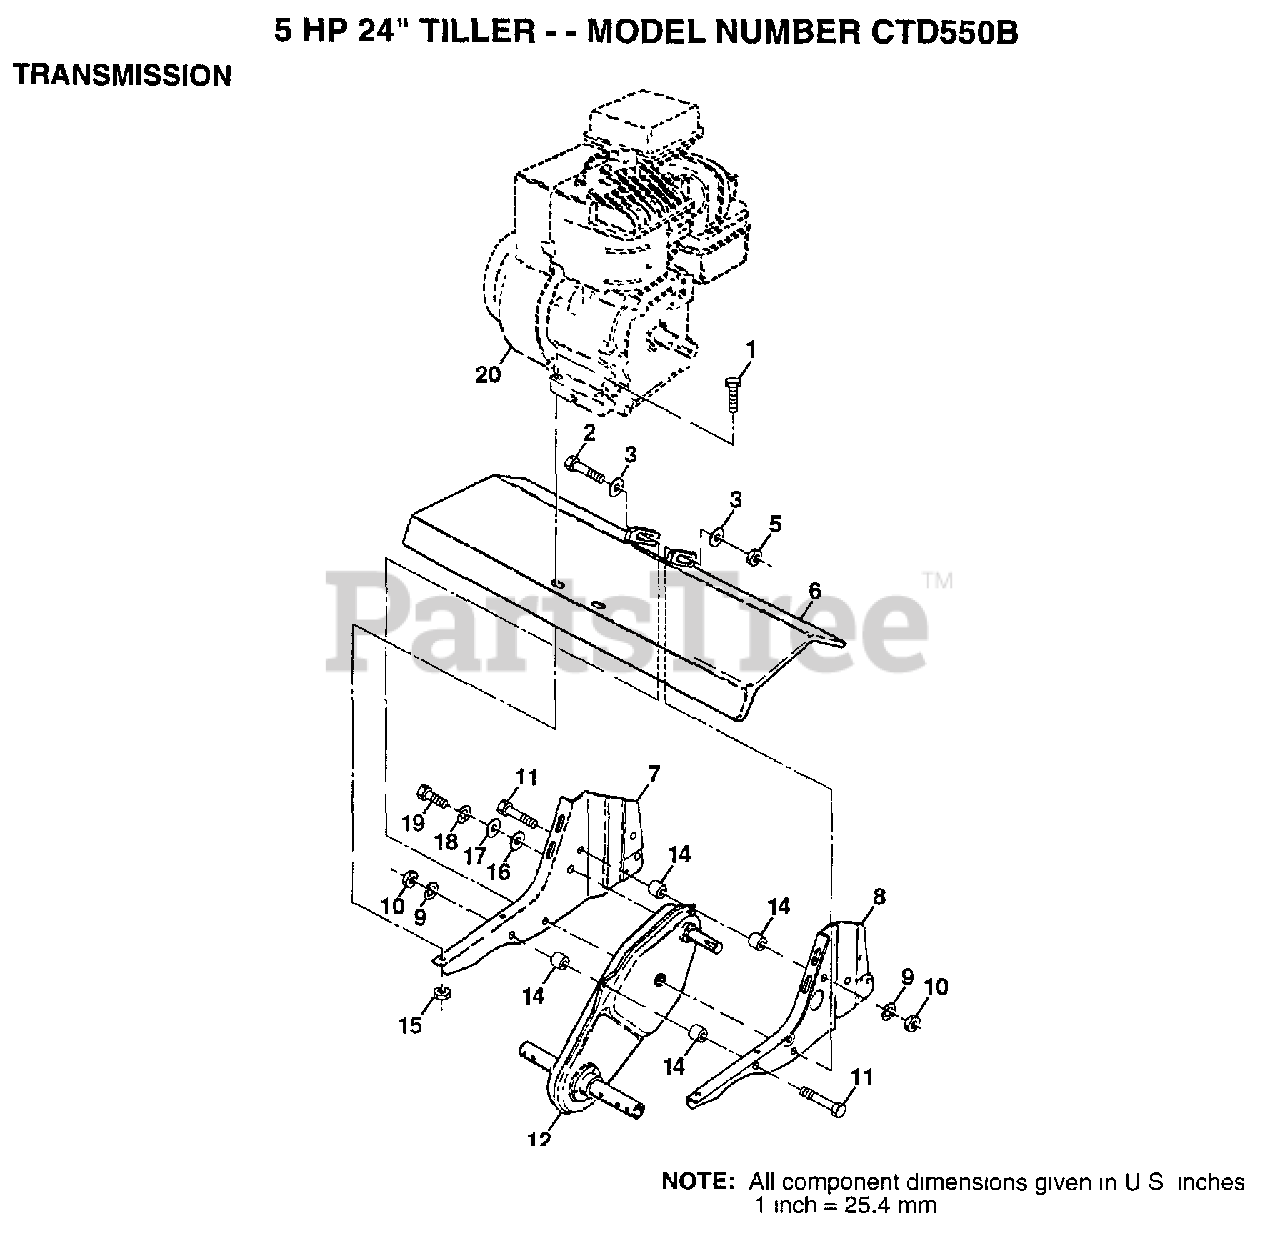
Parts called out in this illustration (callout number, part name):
1	BOLT.HEX.5/16-1.5
2	BOLT HEX 3/8-16
3	WASHER
5	NUT
9	LOCKWASHER
10	NUT.HEX.5/16-18
14	SPLIT SPACER RT
16	WASHER
17	WASHER
18	LOCKWASHER
19	BOLT
